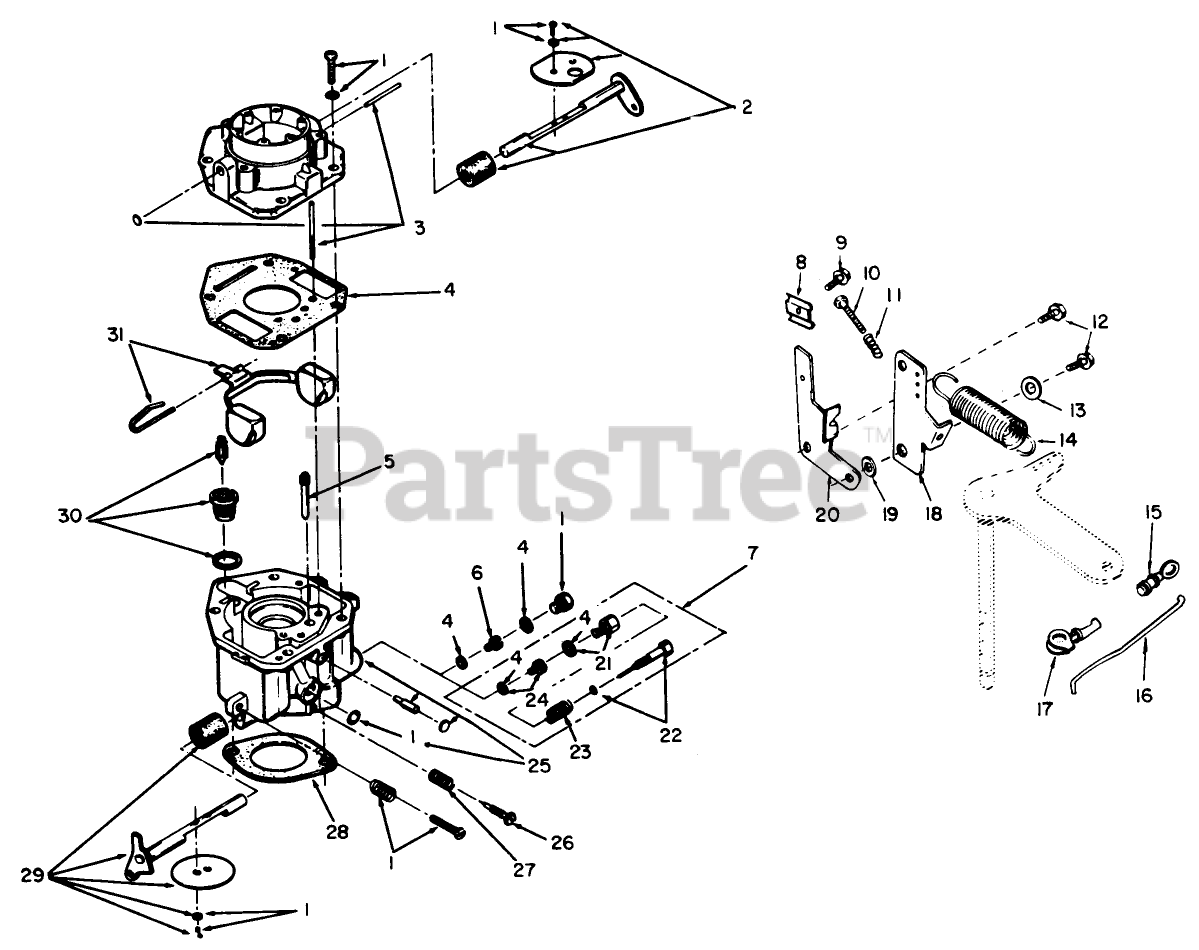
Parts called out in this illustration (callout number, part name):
1	Screw and Plug Kit
2	Choke, Shaft Kit
3	Intake, Air
4	Gasket Kit
5	Jet, Idle
6	Jet, Power
7	Variable Speed Jet Kit-Optional (High Altitude Application)
8	Clamp, Cable
9	Screw, Tapping Hex. Hd.
10	Screw, Tapping Hex Head
11	Spring Idle Setting
12	Screw-Cap Hex Washer Hd.
13	Washer, Flat
14	Spring, Governor
15	Clip, Retaining-Control Rod
16	Rod, Governor Control
17	Clip, Retaining-Control Rod
18	Arm-Governor Control
19	Bushing Control Arm
20	Bracket Cable
21	Retainer, Power Needle (Incl. Gasket)
22	Needle Complete Power
23	Spring, Power Needle
24	PowerJet, Variable (Incl. Gasket)
26	Needle, Idle Adjusting
27	Spring, Idle Adjusting Needle
28	Gasket Carburetor Mounting
29	Throttle Shaft Kit
30	Valve Seat Kit
31	Float Kit
